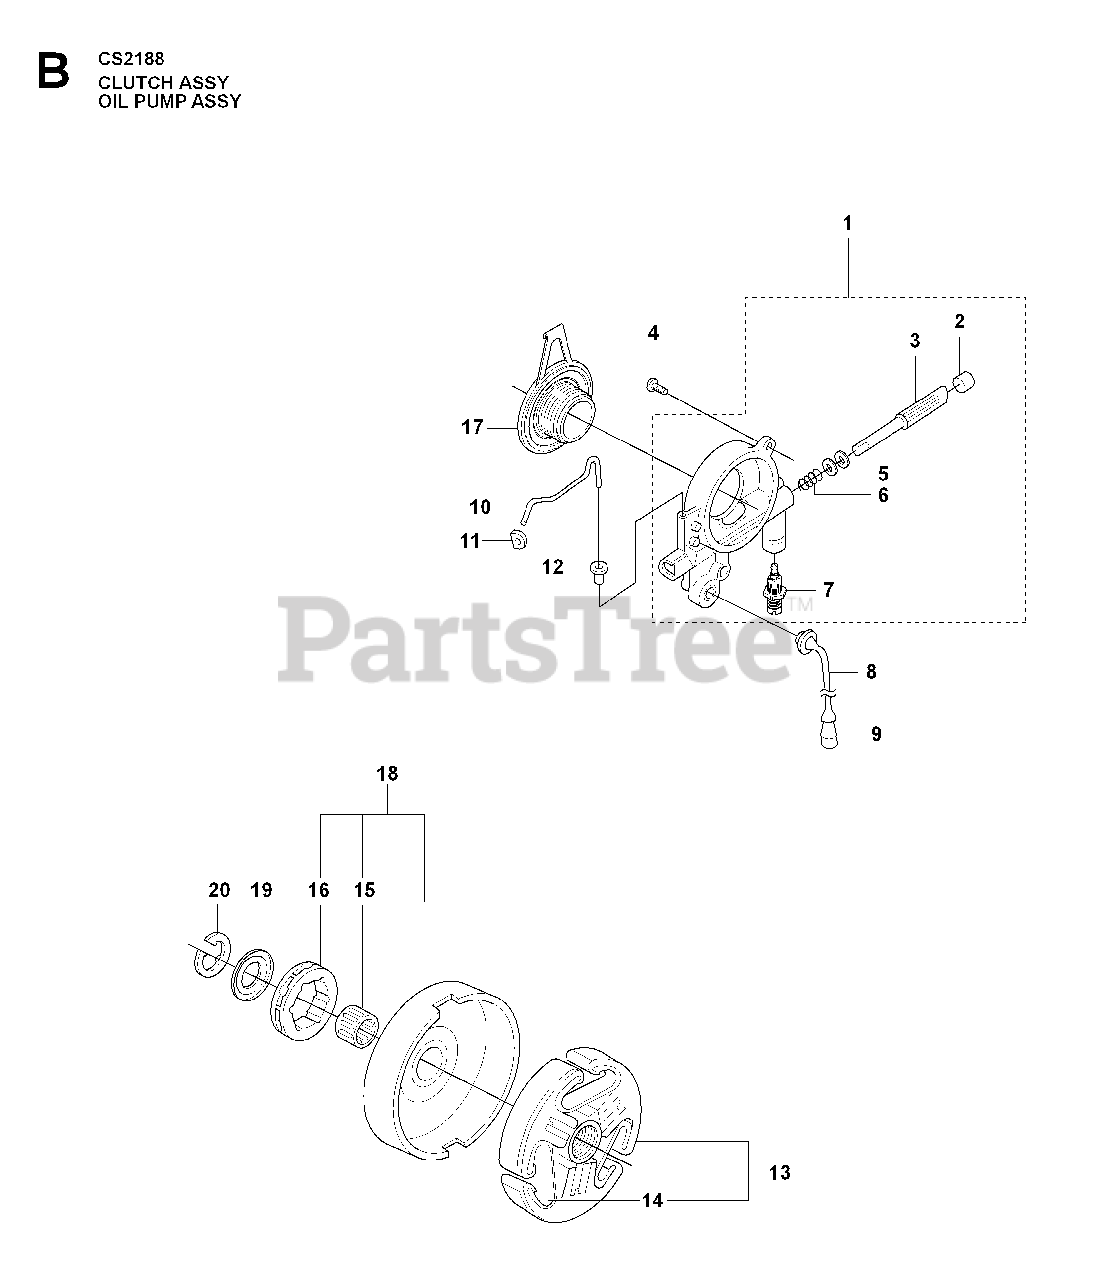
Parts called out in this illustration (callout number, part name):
2	PLUG
3	PUMP PISTON
4	SCREW MC6S 5X16
5	WASHER 6.1X9
6	SPRING
7	INSERT OIL PUMP
9	OIL SCREEN
13	CLUTCH
14	CLUTCH SPRING
15	CLUTCH DRUM BEARING
16	68210 RIMSPROCKET
16	22273 SPROCKET
17	PINION
18	CLUTCH ASSY
20	RETAINING RING
